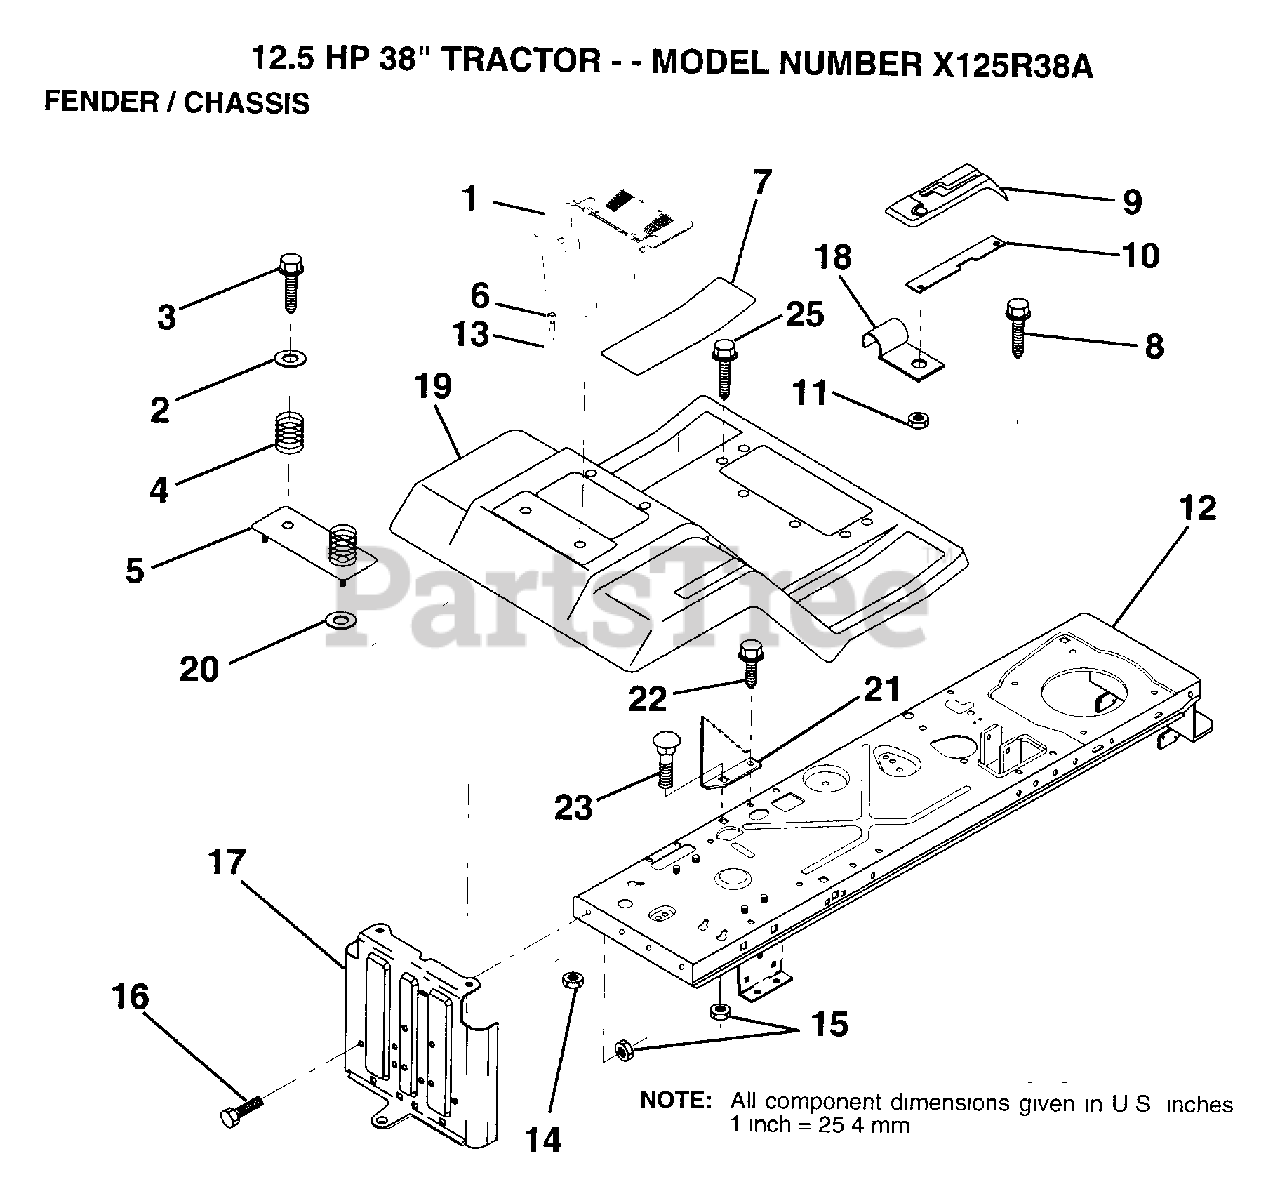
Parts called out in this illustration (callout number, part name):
2	WASHER
3	SCREW
4	SPRING COMPRESSIO
5	"PLATE,FENDER"
6	HOSE CLAMP T
7	PAD FOOTREST
8	SCREW
10	"SHIFT LOCK, BAR"
11	NUT
13	TUBE T
14	NUT
16	BOLT
17	DRAWBAR
18	"CLIP,INSULATOR"
22	SCREW LT
25	SCREW TI
